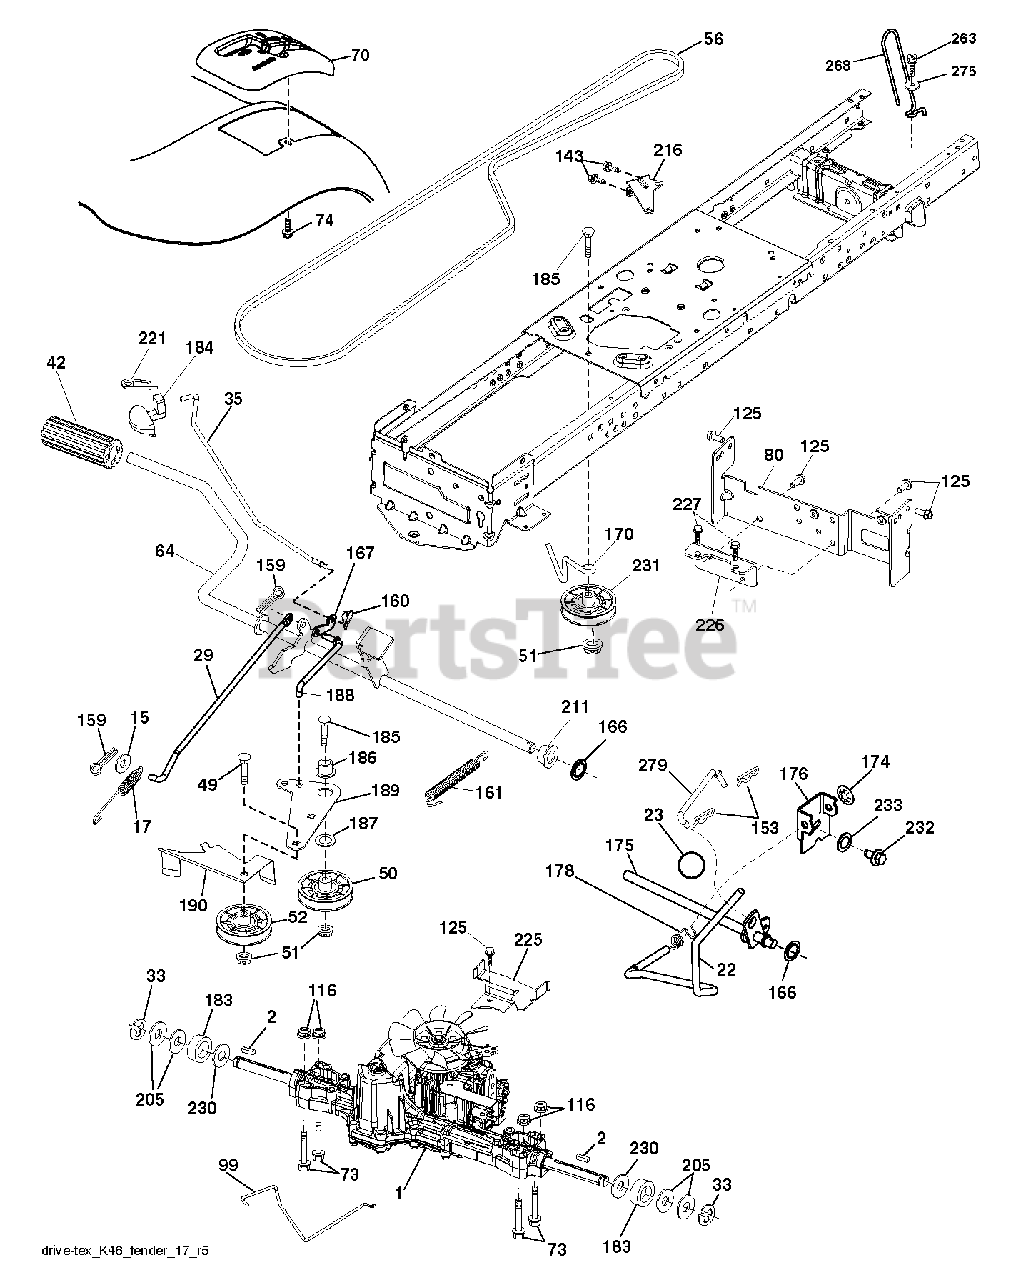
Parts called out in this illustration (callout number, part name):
2	SQUARE KEY
17	SPRING.BRAKE.K46.GREEN
22	ROD.SHIFT.FENDER.TLT.2006
23	KNOB.DUCKHEAD.1/2
29	ROD.BRAKE.K46
33	E-RING LT
35	ROD, BRAKE, PARK
42	PEDAL COVER T
49	BOLT
50	IDLER.FLAT.910.OFFSET
51	NUT LOCK FLG 3/8-16 UNC
52	IDLER.V-GROOVE.910.OFFSET
64	SHAFT.ASM.PEDAL.BRAKE.
70	CONSOLE.SHIFT.STL.HYD.BLACK
74	SCREW.HI-LO.CONSOLE
80	STRAP.TORQUE.K46.K57R.TT
99	ROD.SPRING.BYPASS.K46.LT.Z
116	NUT LOCK HEX FLANGE 5/16-18
125	SCREW
153	RETAINER M
159	COTTER PIN
160	RETAINER CLIP
161	SPRING, RETURN LT
166	NUT.PUSH.625
167	LATCH.BRAKE.SPRING
170	KEEPER.CENTER SPAN.1.688
174	NUT.PUSH.500.2006
175	SHAFT.ASM.SHFT.T2.TLT
176	ARM.CLEVIS.ROD.SHIFT
178	SPRING.SHIFT.GT2006
183	SPACER AXLE
184	HANDLE.PARKING.BRK.PRED.LT.RED
186	SPACER.RETAINER
187	WASHER 12/32X2X10GA
188	LINK.CLUTCH.GROUND.DRIVE
189	BELLCRANK.GROUND.DRIVE.TEX.
190	KEEPER.BELLCRANK.DRIVE
211	BUSHING.SHAFT.BRAKE.HAND
216	BRACKET.PULLEY.IDLER.W/TEX
221	RETAINER.SPRING.CLIP.H
225	KEEPER.BELT.TRANSAXLE.K46
226	BRACKET.MOUNT.TORQUE.K46.TLT
227	SCREW
230	WASHER.HARDENED
231	IDLER.V-GROOVE.1.688.OFFSET
232	BOLT FIN HEX 7/16-14 X 1
233	WASHER SERRATED
263	SCREW, 3/8-16X3/4
275	WASHER
279	LINK.SHIFT.
